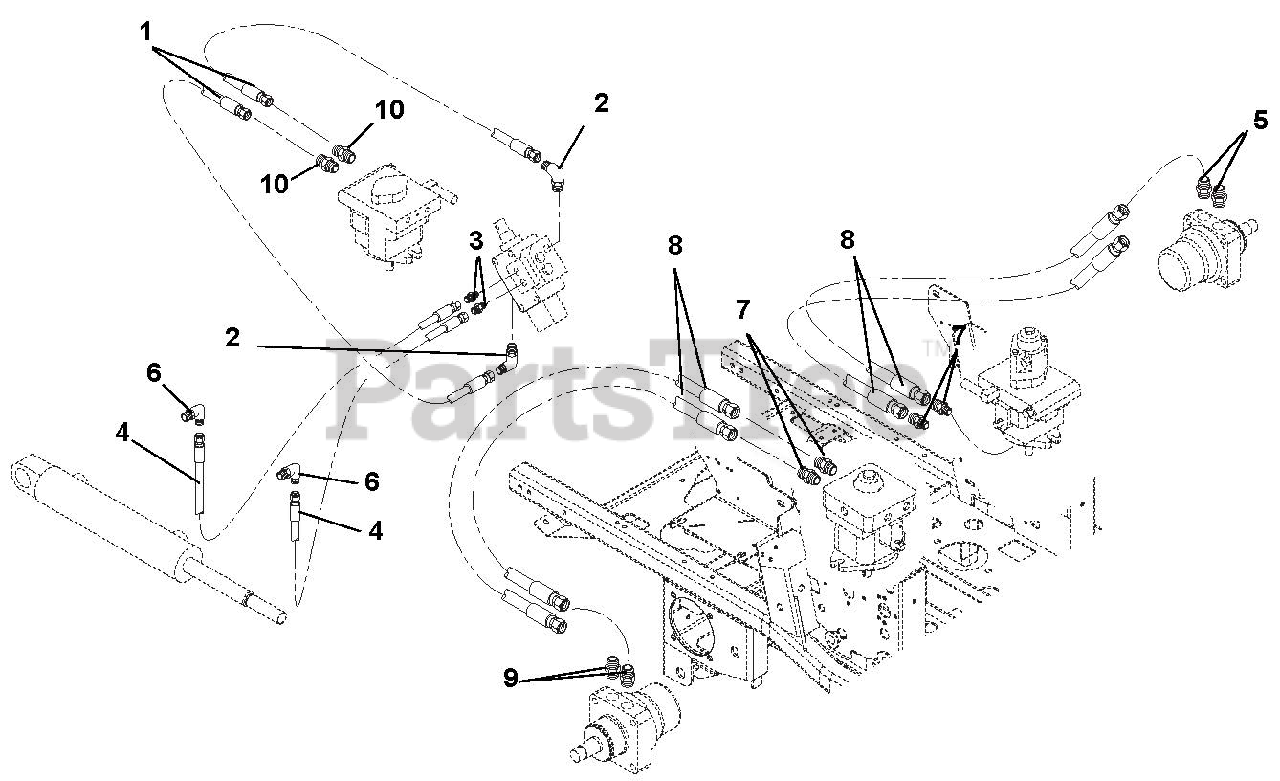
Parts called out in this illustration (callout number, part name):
1	Hose, Hydraulic
2	Hydraulic, Fitting Elbow
3	Adapter
4	Hose, Hydraulic
5	Fitting, Hydraulic Straight
6	Fitting, Hydraulic
7	Adapter, Face Seal 8 x 8 .50 O-Ring
8	Hose, Hydraulic .50
9	Adapter, Hydraulic Steel
10	Fitting, Hydraulic
